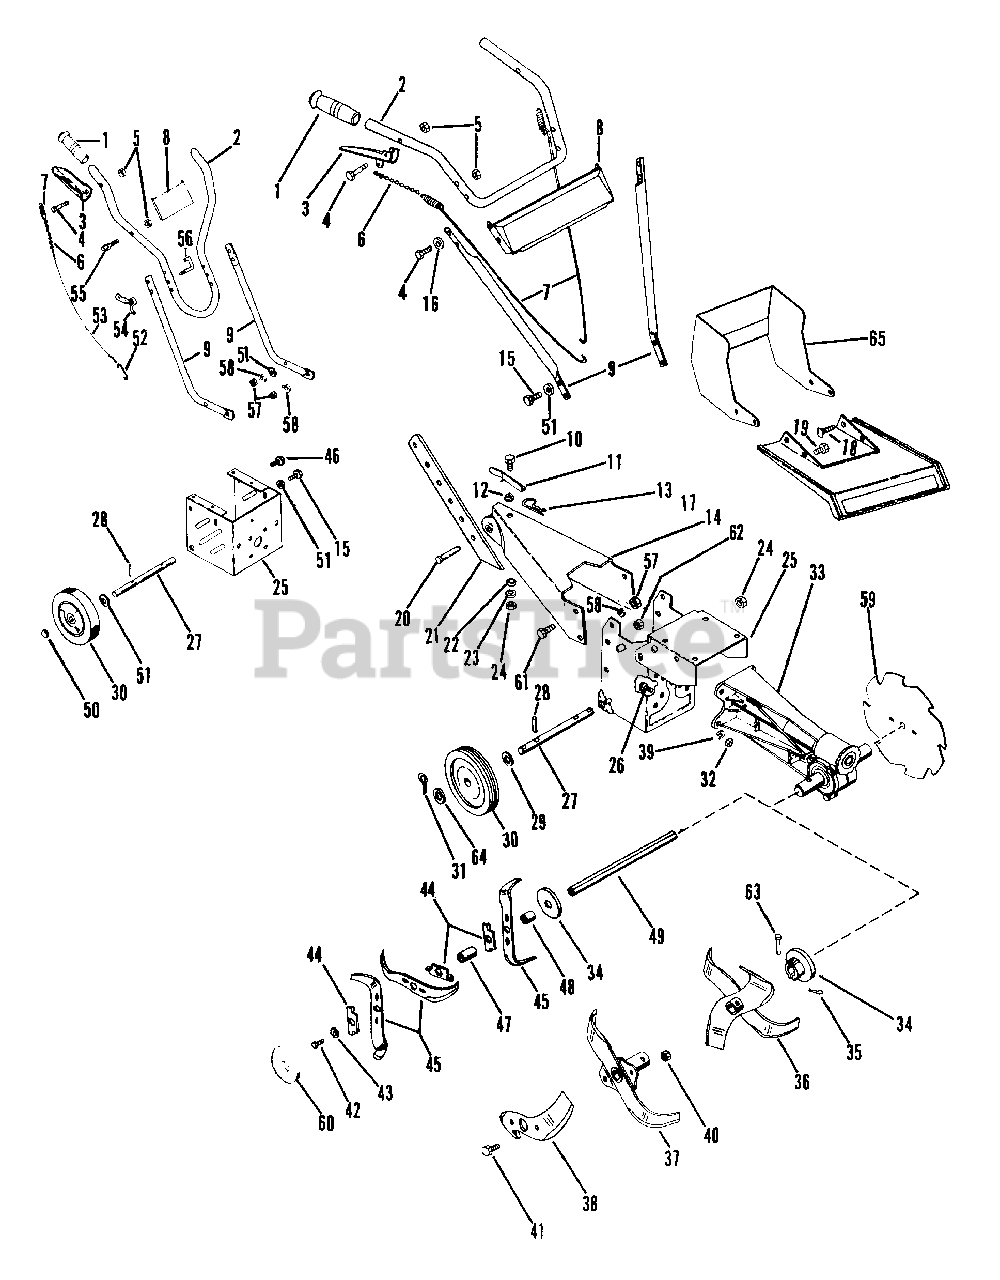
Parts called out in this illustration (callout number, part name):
1	GRIP
2	HANDLEBAR
2	UPPER HANDLEBAR
3	CLUTCH HANDLE
3	Clutch Handle
4	BLT-HEX .25-20X1.50 PL GR5
5	NUT-LK-CTR .250-20 PL
6	CHAIN & CONNECTOR
6	CLUTCH CHAIN
7	SG-TENS .080X.25X31.6 WLD 35
7	SG-TENS .092X.69X1.75 WLD 54
8	HANDLEBAR PANEL
8	NAME PLATE
9	LOWER HANDLE BAR
9	L H LOWER HANDLEBAR
9	R H LOWER HANDLEBAR
10	BLT-HEX .31-18X.75 PL GR2
11	RETAINER CLIP
12	WAVE WASHER .515 X 1.00 X .125
13	PIN-HAIR EXT .12X.31X2.37 PL
14	DEPTH STICK HOLDER
15	BLT-HEX .38-16X1.00 PL
16	WSHR-FL-STL .268X.562X.046 PL
17	TINE HOOD
18	BLT-RDHDSQNK .312-18X.62SHTPL
19	BLT-HEX .31-18X.63 PL GR 2
20	CLEVIS PIN .437/.431X1.50 YWZC
21	DEPTH STICK
22	SPACER BUSHING .5 X .32 X .21
23	WSHR-FL-STL .38X.875X.083 PL
24	NUT-LK .312-18 GR A PL
25	FRAME
26	BLT-HEX .38-16X1.25 PL GR 2
26	SCREW - FLG WIZ LOCK HH PL
27	AXLE ROD
28	PIN-ROLL .125X1.38
28	PIN-ROLL .125X.75
29	SPACER .76 X .51 X .56
30	WHL
30	TIRE 8X1.75
31	PIN-COTR .12 X 1.25 PL
32	NUT-HEX .375-16
32	NUT-LK-FLG .375-16 PL
33	GEAR CASE - CAST IRON
33	GEAR CASE - ALUMINUM
34	DUST CAP
34	DUST CUP
35	PIN-HAIR INT .08X.38X1.42 YWZC
36	R H INNER TINE SPOOL
36	L H INNER TINE SPOOL
37	L H OUTER TINE SPOOL
37	R H OUTER TINE SPOOL
38	R H TURBO-TINE
38	L H TURBO-TINE
39	WSHR-LK .375X.115 HVY PL
40	NUT-LK-TOP .437-14 GR C PL
41	BLT-HEX .44-14X1.00 GR5
42	BLT-HEX .38-24X.75 GR5
43	WSHR-LK .375X.130
44	TINE RETAINER
45	LEFT HAND TINE
45	RIGHT HAND TINE
46	BLT-HEX .38-16X1.75 PL GR2
47	SPACER .747X1.002X1.562
48	SPACER .747X1.002X1.250
49	HEX TINE SHAFT
49	HEX SHAFT
50	CAP, 3/8 ROD YWZC
51	WSHR-FL-STL .38X.875X.083 PL
51	WSHR-FL-STL.406X.812X.065PL
52	LINK
53	CLUTCH CABLE
54	WING NUT, .312-18
55	ROD HANGER EYEBOLT
56	J BOLT
57	NUT-HEX .375-16
58	WSHR-LK .375X.115 HVY PL
59	EDGER
60	WSHR-FL-STL .390X1.500X.125
61	BLT-HEX .38-16X.75 PL GR2
62	NUT-LK-CTR .375-16 GR A PL
63	CLEVIS PIN
64	WSHR-FL-STL .531X1.062X.095 PL
65	SHIELD
